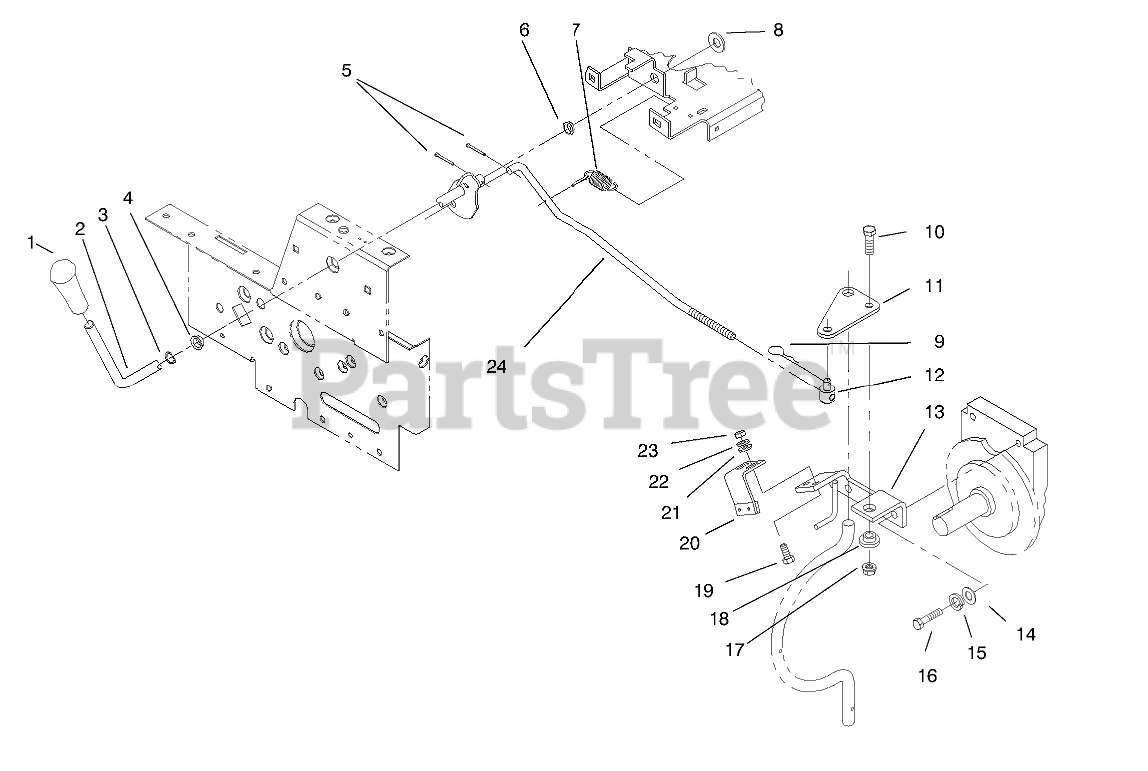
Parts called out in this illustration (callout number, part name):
2	PTO CLUTCH LEVER ASM
3	RING-EXT GRIP
4	BUSHING-NYLINER
5	PIN-COTTER
6	NYLINER BUSHING
7	SPRING
8	SHIM-WASHER
9	PIN-HAIR
10	SCREW-HH
11	PLATE
12	TRUNNION
13	Bracket-PTO
14	WASHER-FLAT
15	WASHER-LOCK
16	SCREW-HH
17	NUT-LOCK, NI
18	SPACER-LIFT LINK
19	SCREW-CARR
20	BRAKE ASM
21	WASHER-FLAT
22	WASHER-LOCK
23	NUT-JAM
24	ROD-PTO CLUTCH
